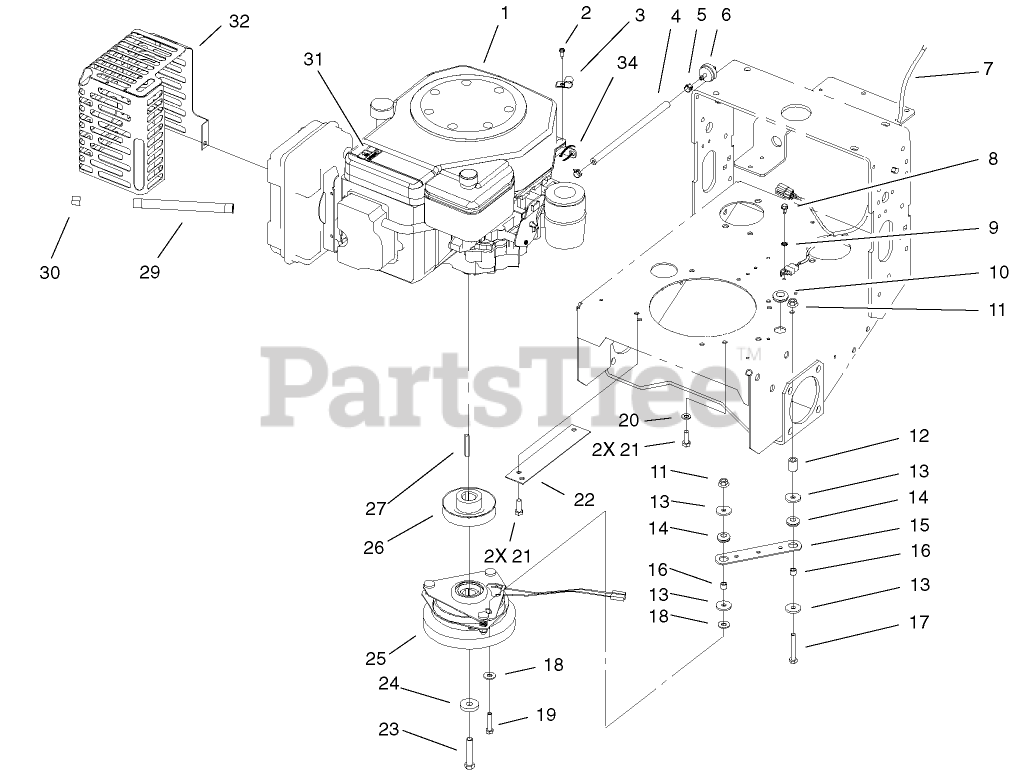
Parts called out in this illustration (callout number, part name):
2	SCREW-SHWH
3	CLAMP-CABLE
4	HOSE-FUEL
5	CLAMP-HOSE
6	FILTER-FUEL
7	HARNESS-WIRE
8	SCREW
9	WASHER-LOCK/EXT
10	GROMMET
11	NUT-HF
12	TUBE-RETAINER
13	WASHER
14	GROMMET
15	STRAP-CLUTCH/BRAKE
16	SPACER
17	SCREW-HH
18	WASHER-FLAT
19	SCREW-HH
20	WASHER-PLAIN
21	SCREW-HH
22	COVER-PULLEY
23	SCREW-HH
24	WASHER
25	CLUTCH/BRAKE
26	Pulley
27	KEY-SQUARE
29	PIPE-NIPPLE
30	CAP-PIPE
31	DECAL-SURFACE, HOT
32	Guard-Muffler
34	TIE-CABLE
